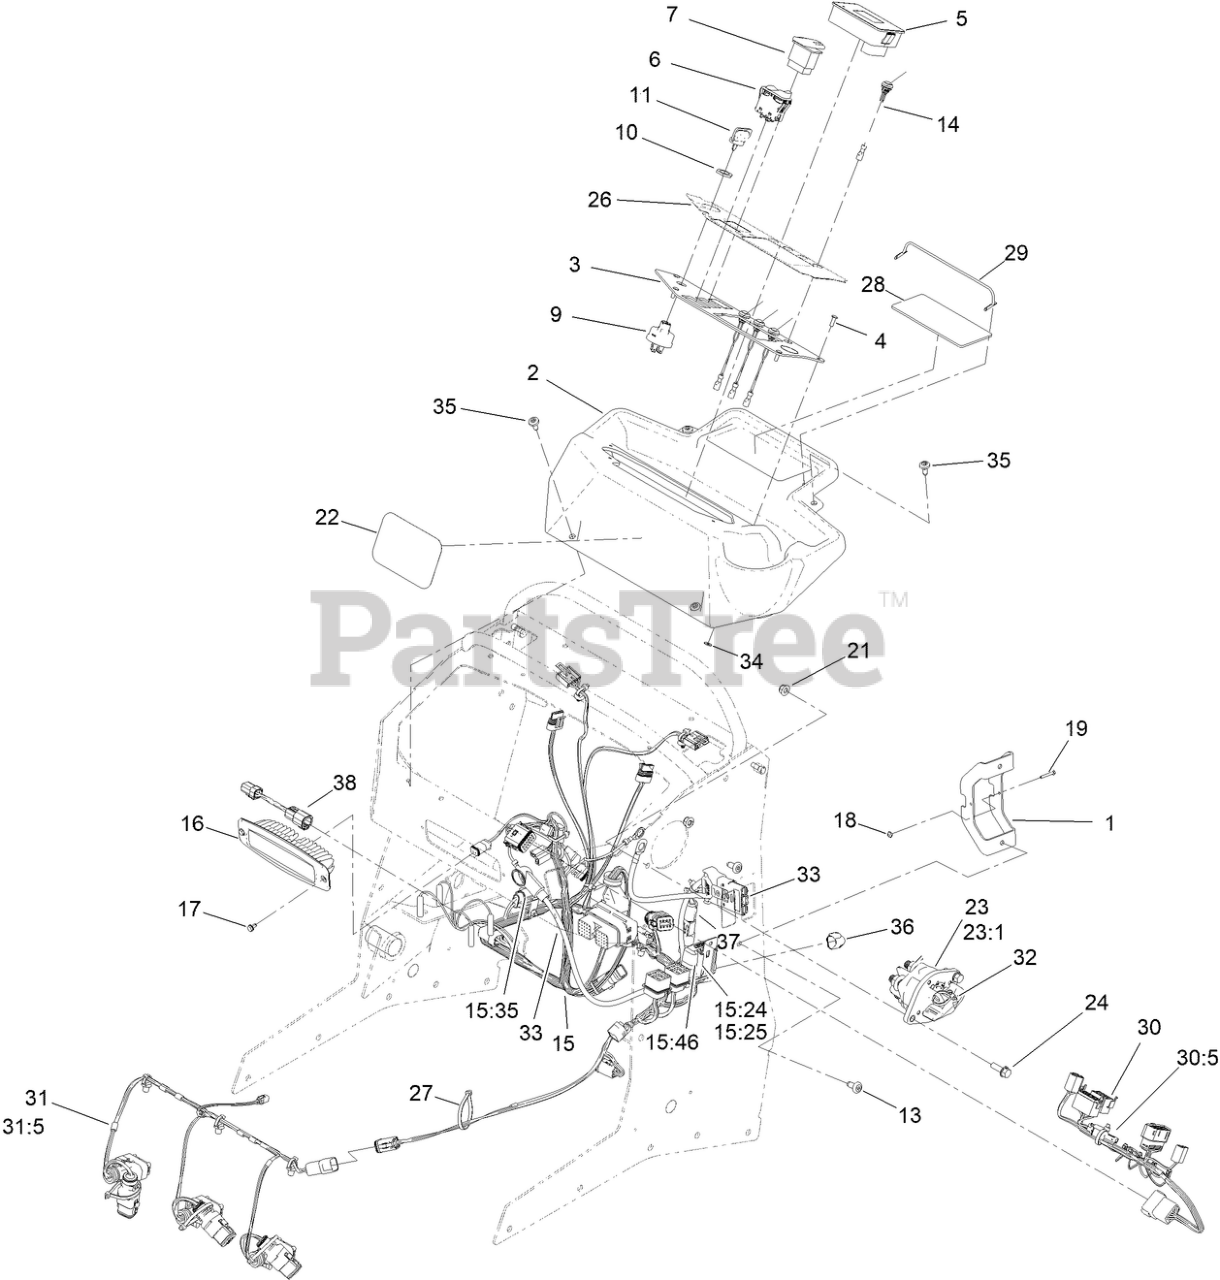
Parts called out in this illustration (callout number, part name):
1	BRACKET-CHARGER, DUAL
2	DASH-CONTROL PANEL
3	PLATE-CONTROL PANEL
4	RIVET-POP
5	TDM 2002
6	SWITCH-ROCKER, (ON)-ON-OFF
7	SWITCH
9	SWITCH-KEY, SPST
11	KEY-IGNITION
14	SWITCH-PUSHBUTTON
15	HARNESS-WIRE, MAIN
15:24	FUSE-MINI BLADE, 2 AMP
15:35	FUSE-BLADE, 10A
15:46	FUSE-MINI BLADE, 7.5 AMP
16	MOUNT-FLUSH, LIGHT
17	SCREW-HWH
18	NUT-HEX
19	SCREW
21	NUT-HF, NI
22	DECAL
23	SWITCH-DISCONNECT
23:1	NUT-HF
24	SCREW-HHF
26	DECAL-PANEL, CONTROL
27	TIE-CABLE
28	PAD-RUBBER, W/ADHESIVE
29	STRAP-ELASTIC
30	HARNESS-WIRE, CONTROL PANEL
30:5	RESISTOR-120 OHM
31	HARNESS-WIRE, DECK
31:5	RESISTOR-120 OHM
32	TIE-CABLE
33	HARNESS-WIRE, CHARGER PORT
34	WASHER-PLAIN
35	SCREW-SHOULDER
36	CAP-PLUG, 3 WAY
37	FERRITE-SNAP ON
38	HARNESS-WIRE, JUMPER
